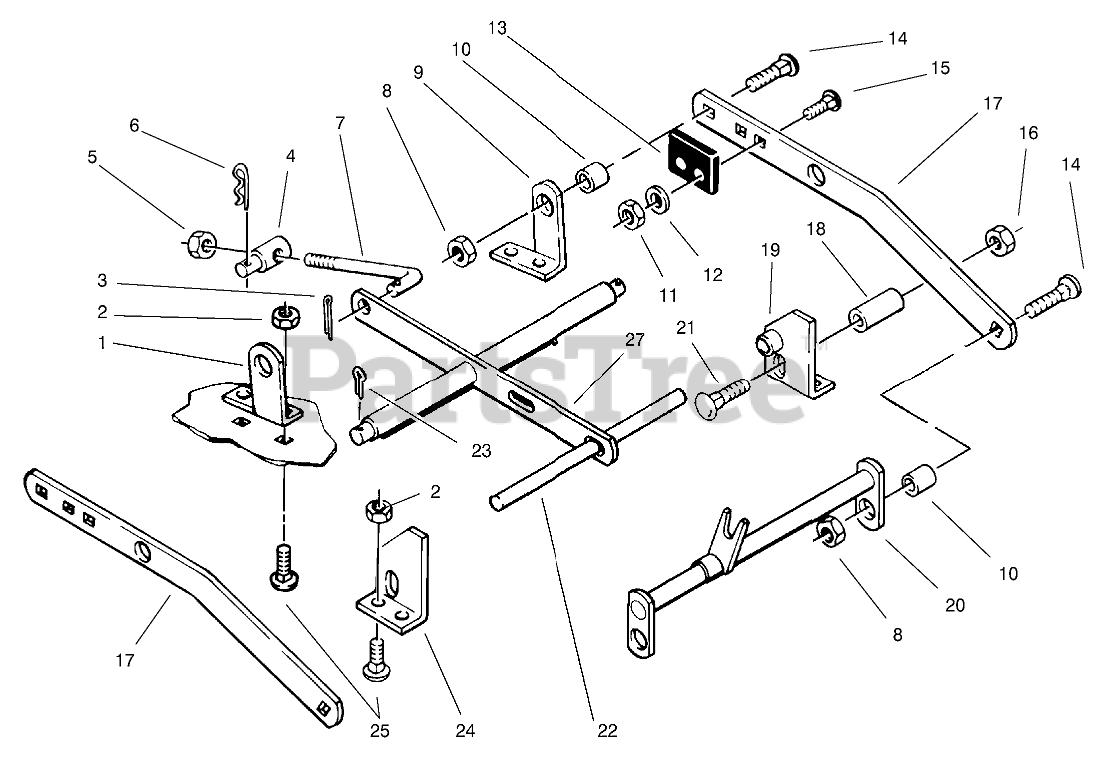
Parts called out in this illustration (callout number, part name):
1	RH BRKT-DECK REAR (RED)
2	NUT-LOCK, NI
3	PIN-COTTER
4	TRUNNION-LIFT
5	NUT-LOCK, NI
6	Hairpin
7	ROD-LEVEL ADJUST
8	LOCKNUT-FLANGE
9	LH BRKT-DECK REAR (RED)
10	SPACER
11	NUT-LOCK, NI
12	WASHER-FLAT
13	BUMPER
14	BOLT-CARR
15	SCREW-CARR
16	NUT-LOCK, NI
17	BAR DRAFT (RED)
18	SPACER
19	WA BRACKET FT L (RED)
20	WA HITCH (RED)
21	BOLT-CARR
22	SHAFT FRONT (RED)
23	PIN-COTTER
24	WA BRACKET FT R (RED)
25	BOLT-CARR
27	LEVELER WA (RED)
